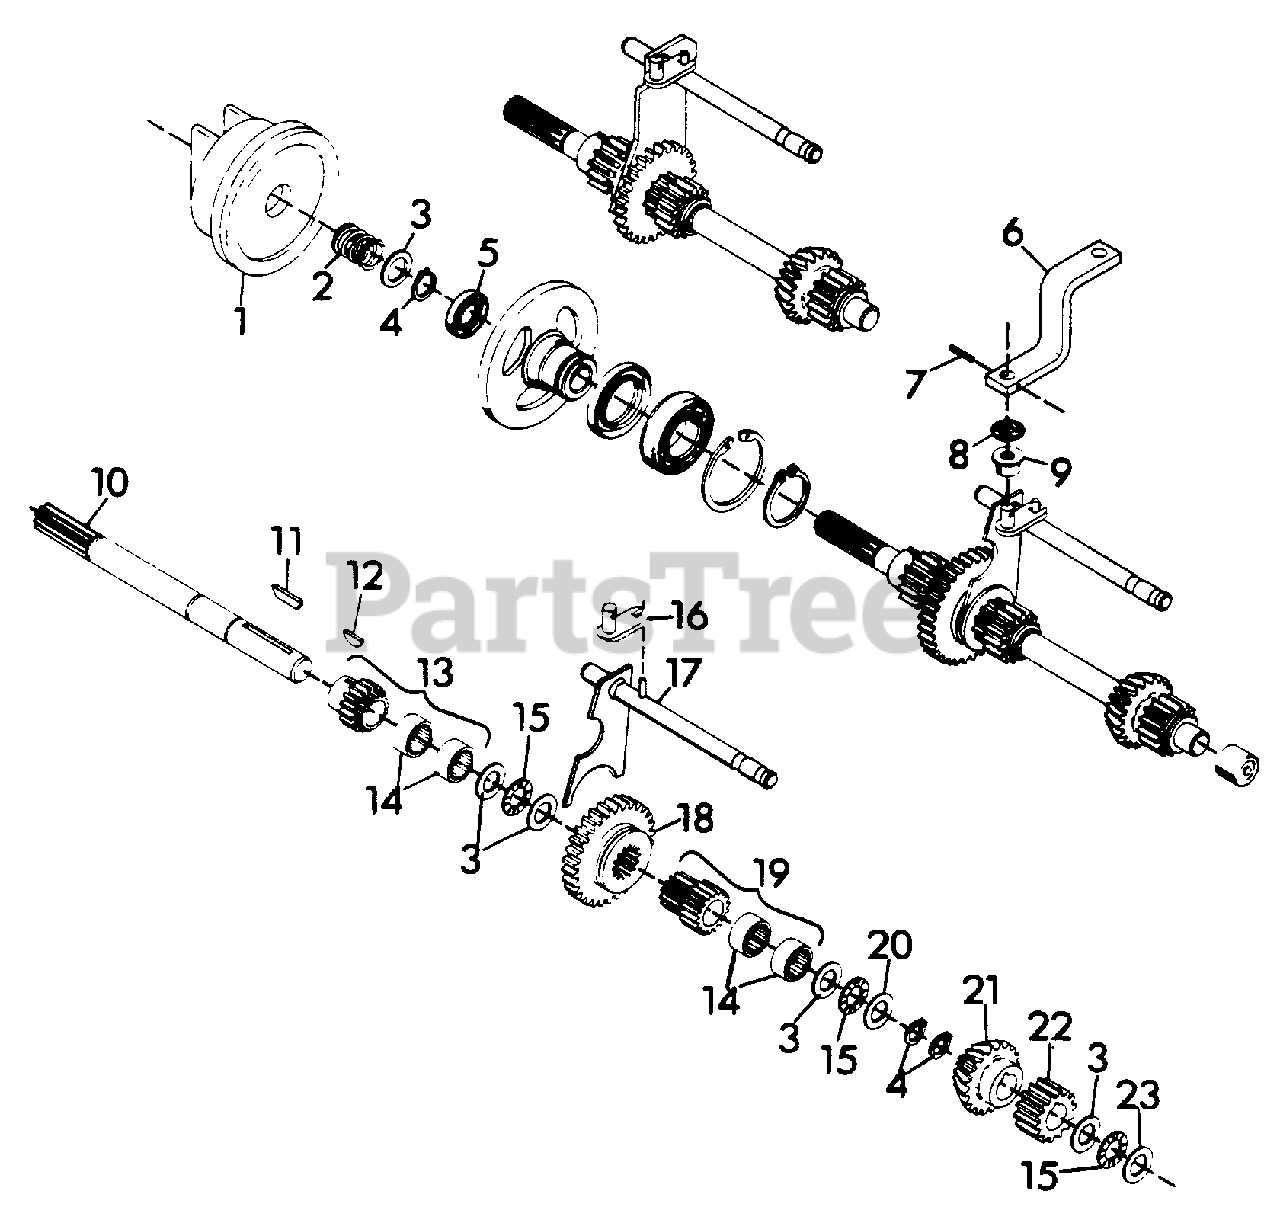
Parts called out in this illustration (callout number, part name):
1	NUMBER 11 - FWD-REV CLUTCH ASSEMBLY
2	SPRING, COMP. TYPE 1.0X.80X36 LB/IN
3	RACE, BEARING THRUST .752X1.240X.03
4	RING, RETAINING .750 SHAFT
5	SEAL, OIL .750X1.625X.250
6	ARM, SHIFTER
7	PIN, SPRING .187X1.000
8	WASHER, FELT
9	BUSHING, 2-SPEED
10	SHAFT, SPLINED FORWARD CLUTCH
11	KEY, WOODRUFF .187X1.25 HARD #19
12	KEY, WOODRUFF .187X.625 HARD #61
13	ASSEMBLY, GEAR AND BEARING
14	BEARING, NEEDLE .75X1.00X.50
15	BEARING, NEEDLE THRUST
16	WELDMENT, SHIFTER
17	WELDMENT, SHIFT RAIL
18	GEAR, SPUR 2 SPEED 10 DP 36T
18	GEAR, SPUR 2 SPEED 10 DP 26T
19	ASSEMBLY, GEAR AND BEARING
20	RACE, BEARING THRUST .060
21	GEAR, BEVEL
22	GEAR, 10 DP 16 TEETH X .750
23	RACE, BEARING THRUST .095
